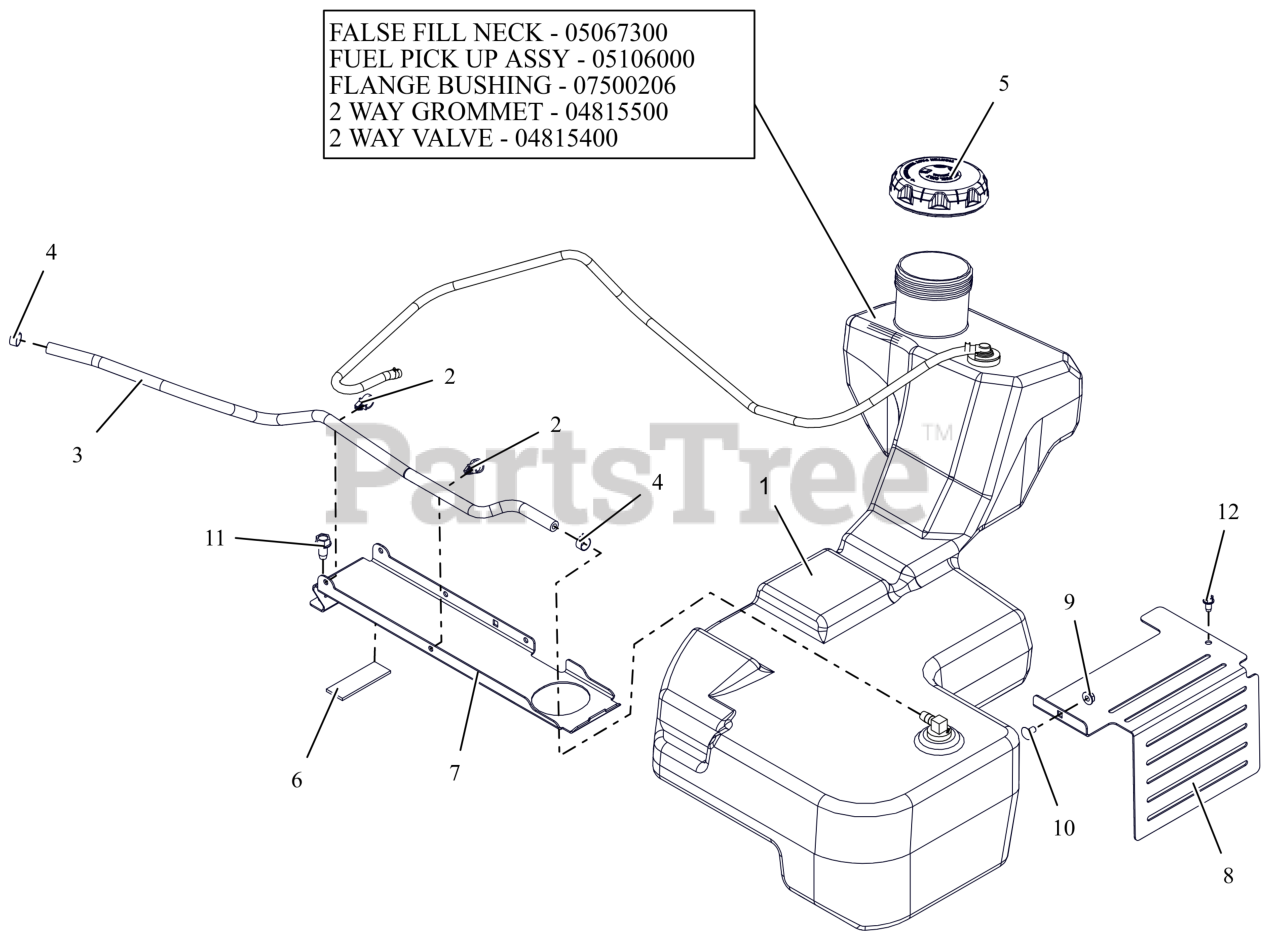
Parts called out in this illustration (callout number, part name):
1	ASM, FUEL TANK-HD
1	INSERT, FUEL NECK FALSE FILL
1	ASM, HD FUEL PICK-UP
1	GROMMET, 2-WAY
1	BSHG-FLG .375X1.062X.625 NITR
1	VALVE, 2-WAY
2	ROUTING CLIP (1/2" ID)
3	HOSE, .25 LOW-PERM BULK GAS
4	CLAMP, FUEL LINE
5	CAP, FUEL VENTIN AUTOLOCK
6	PAD,RBR 1.0"X3.0" W/ADHESIVE
7	BRKT, FUEL TANK HOLD DOWN
8	GUARD, TRANSAXLE FAN LH (BLACK)
9	NUT-LK-CTR-FLG .25-20 ZC120
10	BLT, RHSSN.25-20X.500 G5 ZCC
11	SCR,TAP .375-16X.75 HWH TR ZCC
12	SCR-TAP .25-20X.50 HWH ZCC
